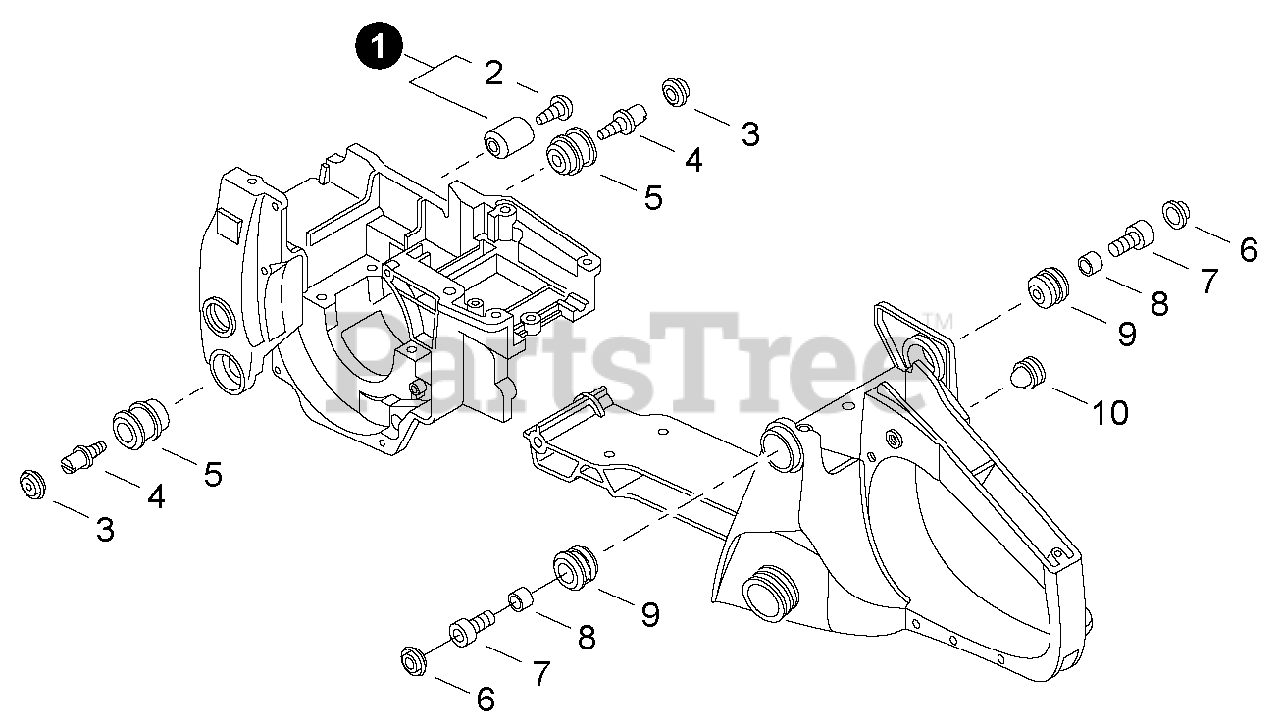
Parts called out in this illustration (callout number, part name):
1	CHAIN CATCHER KIT
2	SCREW - 5X20 -- TAPPING
3	CAP, CUSHION
6	CAP, CUSHION
7	SCREW - 4X20
